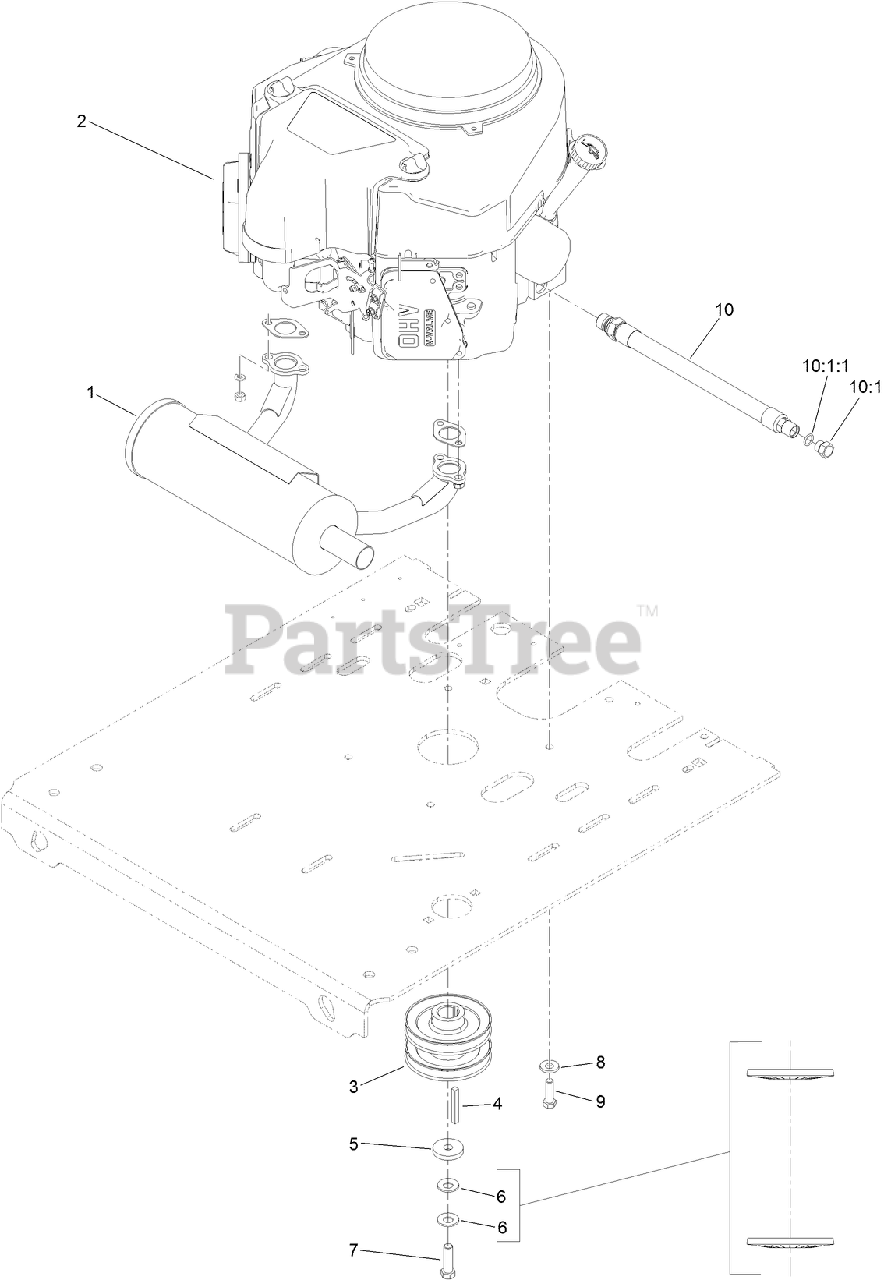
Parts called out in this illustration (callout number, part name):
1	MUFFLER-HORIZONTAL
3	PULLEY
5	WASHER-CLUTCH
6	WASHER-SPRING
7	SCREW-HH, W/LOCTITE
8	WASHER-BELLEVILLE
9	SCREW-HH
10	ENGINE OIL DRAIN HOSE ASM
10:1	PLUG-HH
10:1:1	O-RING
